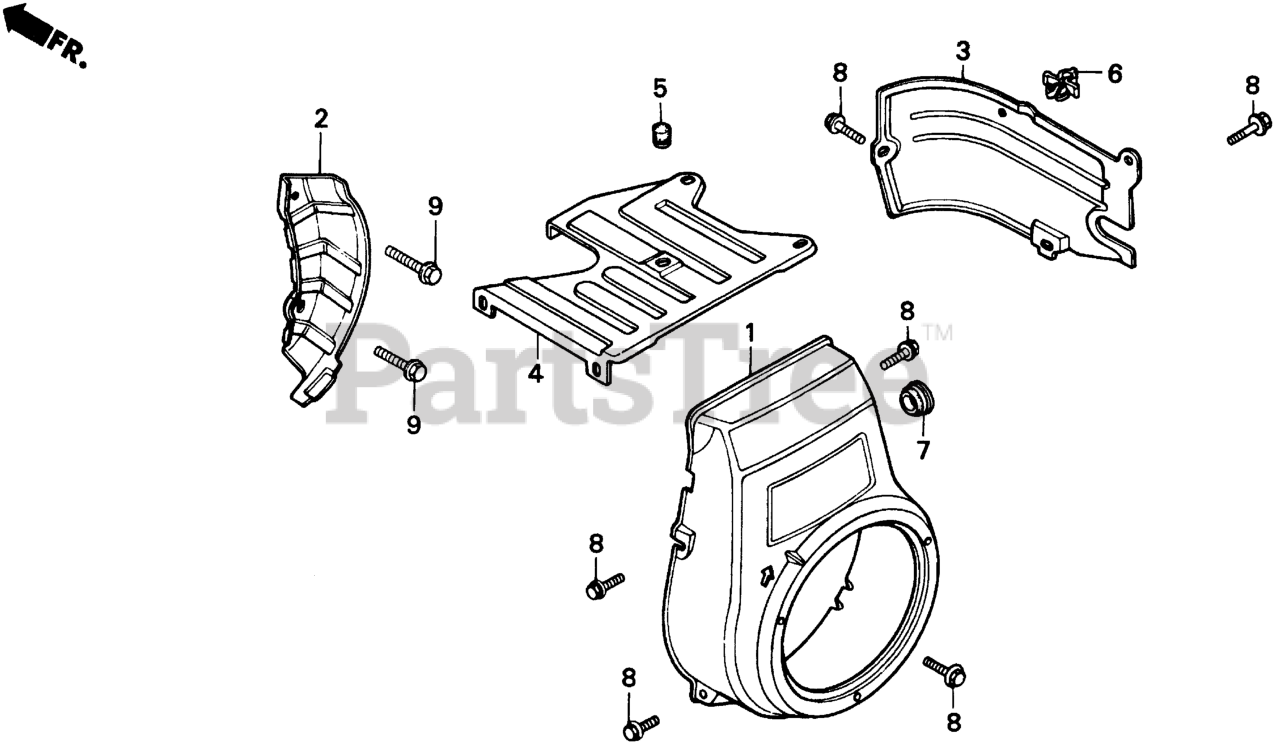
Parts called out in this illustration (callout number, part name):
1	COVER, FAN *R280* (POWER RED)
2	PLATE, SIDE
3	SHROUD
4	COVER, TOP
5	GROMMET, TOP COVER
6	CLIP, IGNITION WIRE (8MM)
7	GROMMET, DRAIN HOLE
8	BOLT, FLANGE (6X12) (CT200)
9	BOLT, FLANGE (8X20)
